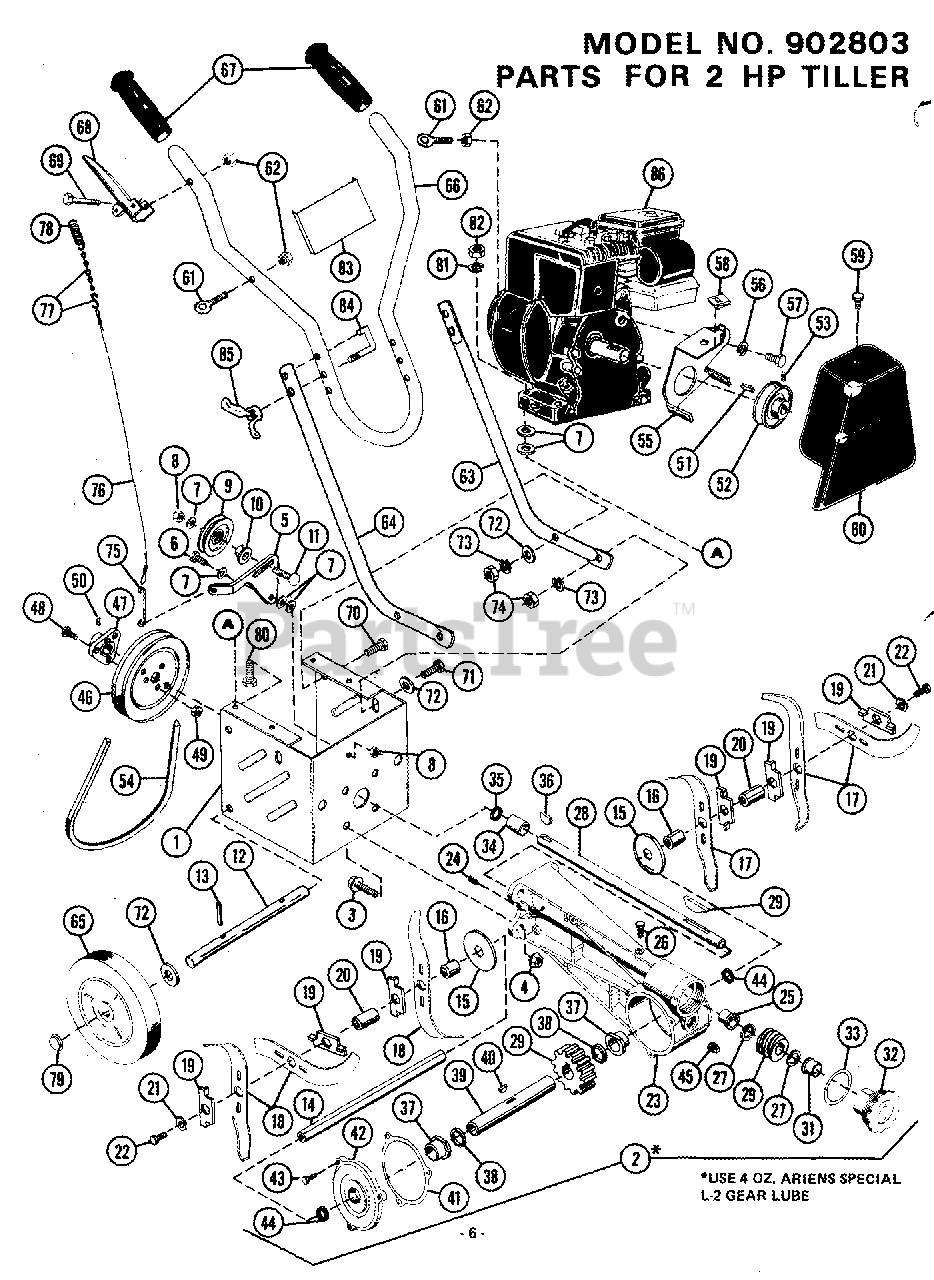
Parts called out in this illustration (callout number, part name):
1	FRAME
2	GEAR CASE - ALUMINUM
3	SCREW - FLG WIZ LOCK HH PL
4	NUT-LK-FLG .375-16 PL
5	IDLER BRACKET
6	BLT-HEX .31-18X1.00 PL GR 2
7	WSHR-FL-STL.38X.875X.083 YWZC
8	NUT-LK .312-18 GR A PL
9	IDLER
10	BRG-CONE ROLLER 50MMX21.5MM
11	BLT-RDHDSQNK .31-18X1.38SHT PL
12	AXLE ROD
13	PIN-ROLL .125X.75
14	HEX TINE SHAFT
15	DUST CUP
16	SPACER .747X1.002X1.250
17	LEFT HAND TINE
18	RIGHT HAND TINE
19	TINE RETAINER
20	SPACER .747X1.002X1.562
21	WSHR-LK .375X.130
22	BLT-HEX .38-24X.75 GR5
23	GEAR CASE
24	BREATHER
25	BSHG-FLG ??X??X??
26	BLT-SCRHFWH .38-16X.50 PL
27	WSHR-HDND-THRST .755X1.40X.062
28	WORM SHAFT
29	KEY-FTHR .188X1.38X.188
30	WORM & WORM GEAR SERVICE ASSEM
31	BSHG-FLG .750X1.000X.750X1.132
32	ADJUSTMENT PLUG
34	BSHG-SLV ??X??X??
35	SEAL .750X1.000X.125
36	KEY-WDRF .188X.875X.375 SAE11
37	BSHG-FLG .500X.750X.750X1.000
38	WASHER, 1.007 x 1.542 x .062 2
39	SUB SHAFT
40	KEY-WDRF .188X.625X.25 SAE 61
42	BEARING FLANGE
43	BLT-SERHFWH .31-18X.62 PL
44	SEAL 1.000X1.980X.375
45	PIPE PLUG
47	HUB
48	BLT-SERRDHD SL .31-18X.75 YZ
49	NUT-FLG. .312-18 PL
50	SCR-SET .25-20X.25 SKHCUP OH
51	KEY-SQ .188X1.0X.188 SAE 8630
52	ENGINE SHEAVE
53	SET SCREW
54	V-BELT, 4L-RAW EDGE
55	BELT FINGER & COVER BRACKET
56	WSHR-LK .500X.151 HVY PL
57	BLT-HEX .75-16X2.50 PL GR5
58	NUT-SPEED U-TYPE .312-18
59	BLT-HEX .31-18X.50 PL GR2
60	BELT COVER
61	ROD HANGER EYEBOLT
62	NUT-LK-CTR .250-20 PL
63	L H LOWER HANDLEBAR
64	R H LOWER HANDLEBAR
65	TIRE 8X1.75
66	UPPER HANDLEBAR
67	GRIP
68	CLUTCH HANDLE
69	BLT-HEX .25-20X1.50 PL GR5
70	BLT-HEX .38-16X1.75 PL GR2
71	BLT-HEX .38-16X1.00 PL
72	WSHR-FL-STL.406X.812X.065PL
73	WSHR-LK .375X.115 HVY PL
74	NUT-HEX .375-16
76	CLUTCH CABLE
77	CHAIN & CONNECTOR
78	SG-TENS .092X.69X1.75 WLD 54
79	CAP, 3/8 ROD YWZC
80	BLT-HEX .62-11X2.25 GR2
81	WSHR-LK .312X.097 PL HVY
83	NAME PLATE
85	WING NUT, .312-18
